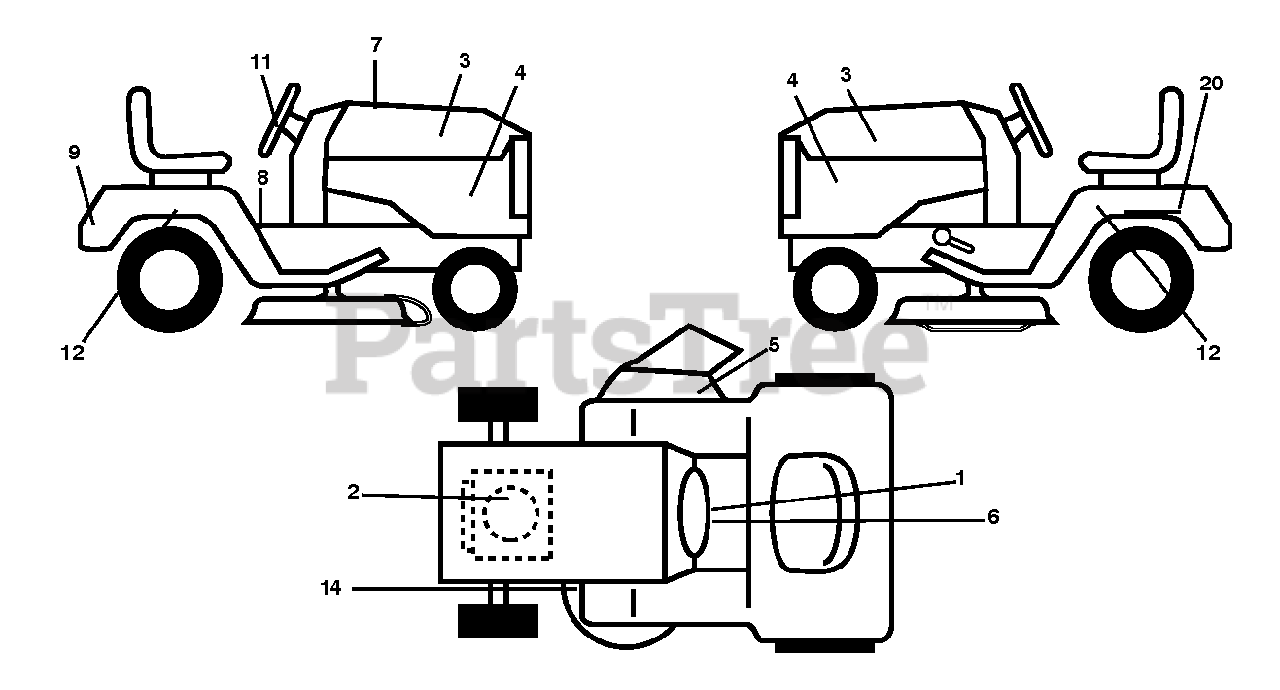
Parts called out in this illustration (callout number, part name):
1	DECAL, WARNING SPARK ARRESTOR
2	DECAL.ENG.BS.20HPXRD.SL.278416
3	DECAL.HOOD.POULAN.PRO.SET
4	DECAL.SDPNL.RH/LHPAIR.20H42.
5	DECAL.MOWER.WARN.KEEP.HAND.AWY
8	DECAL.FENDER.WARNING.ENGLISH
9	DECAL.REAR.FNDR.LOGO.POULAN.PR
11	DECAL.STEER.WHEEL.POULAN.PRO
14	DECAL.V-BELT.SCH.42/46"MEC/ELE
20	DECAL BTRY SYMBOLS
